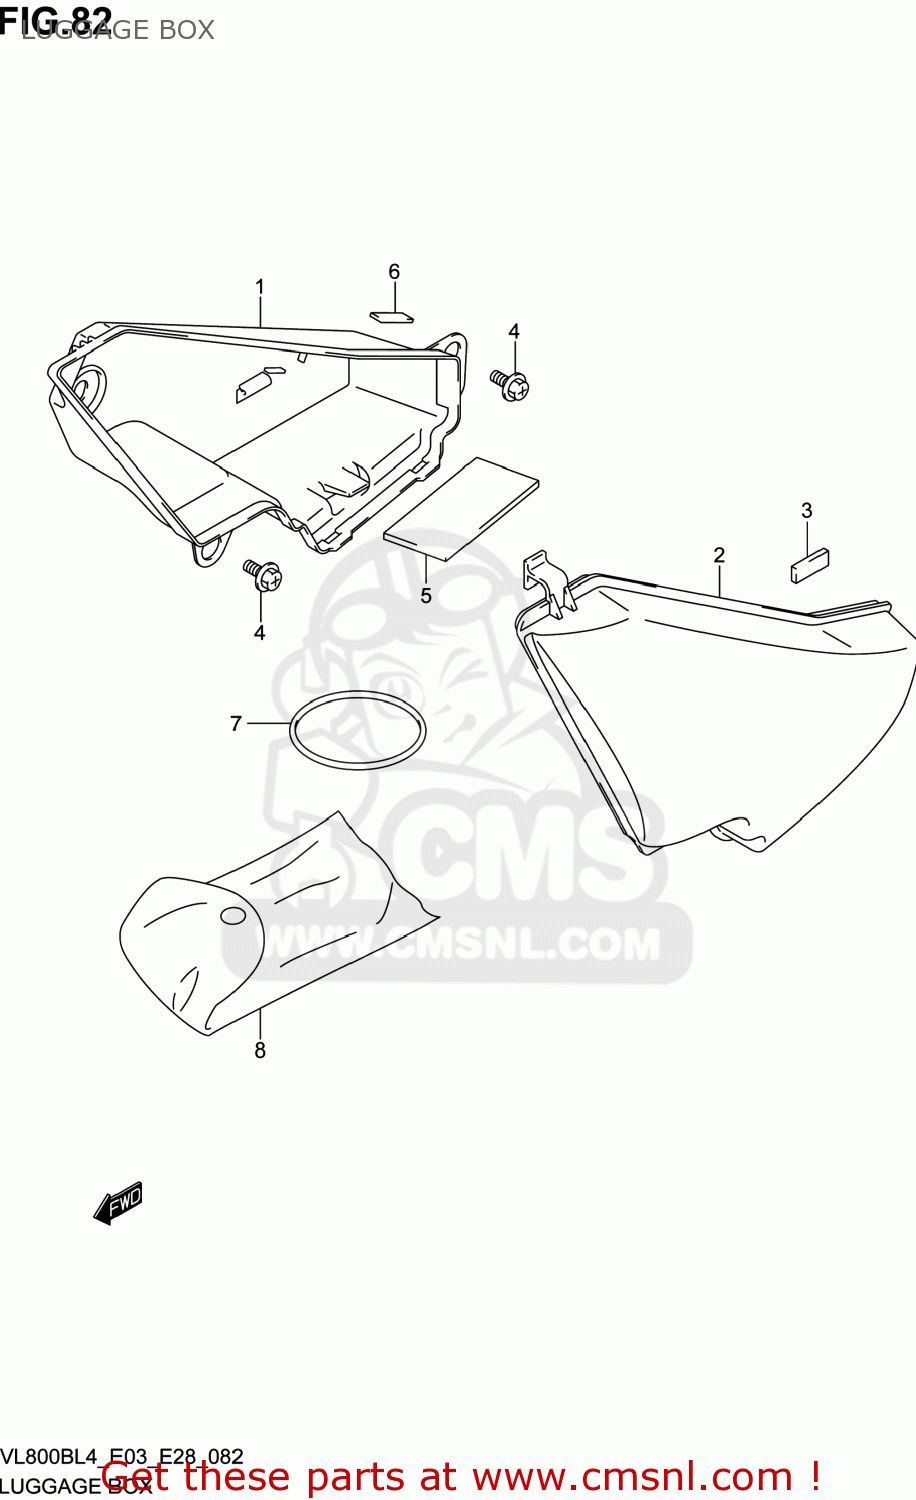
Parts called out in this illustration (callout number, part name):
1	BODY,LUGGAGE BOX
2	LID,LUGGAGE BOX
3	CUSHION,LUGGAGE BOX NO.2
4	BOLT(6X12)
5	PROTECTOR,BATTERY
6	CUSHION
7	O RING(D:3.5,ID:62.6)
8	TOOL ASSY
